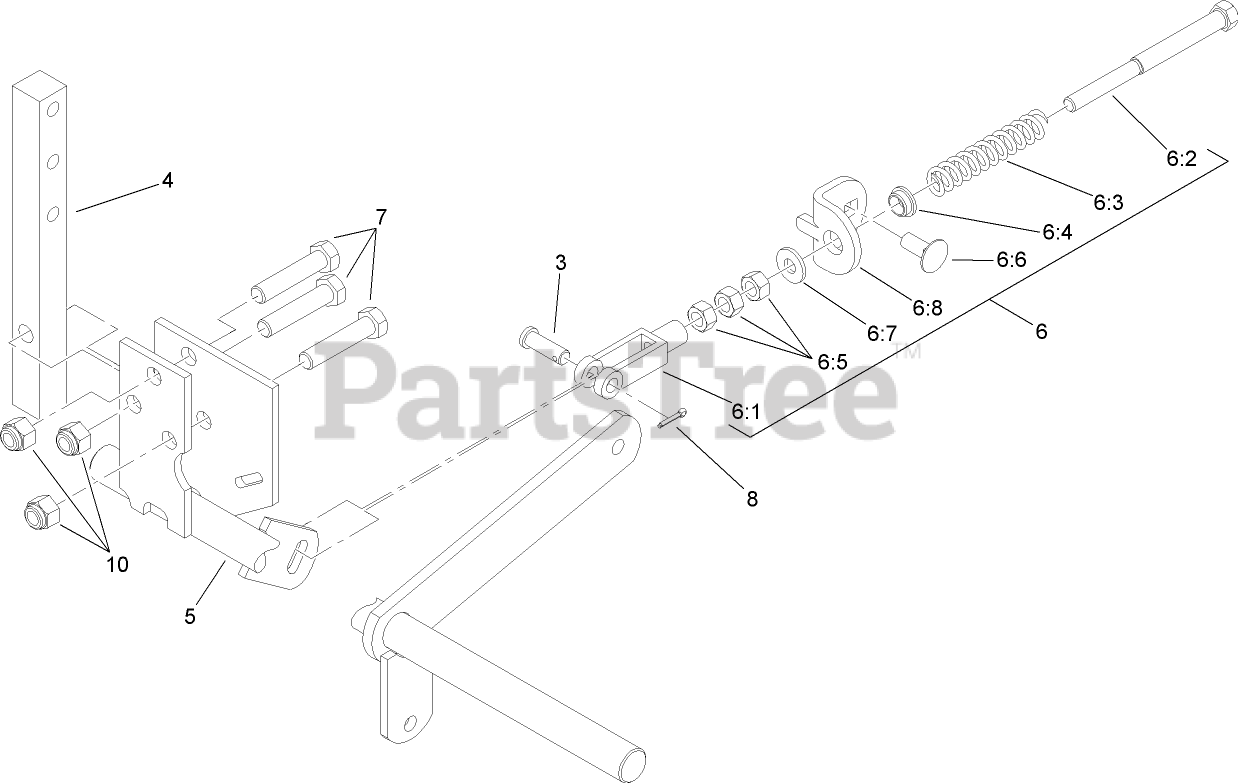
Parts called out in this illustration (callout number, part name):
3	PIN-CLEVIS
4	ARM-SHAFT, CONTROL
5	CONTROL-MOTION, RH
6	NEUTRAL RETURN ASM
6:1	YOKE-ADJUSTABLE
6:2	BOLT-RETURN, NEUTRAL
6:3	SPRING-RETURN, NEUTRAL
6:4	BUSHING-NYLON, FLANGED
6:5	NUT-HEX
6:6	SCREW-CARR
6:7	WASHER-FLAT
6:8	TAB-ADJUSTMENT
7	SCREW-HH
8	PIN-COTTER
10	NUT-LOCK, NI
